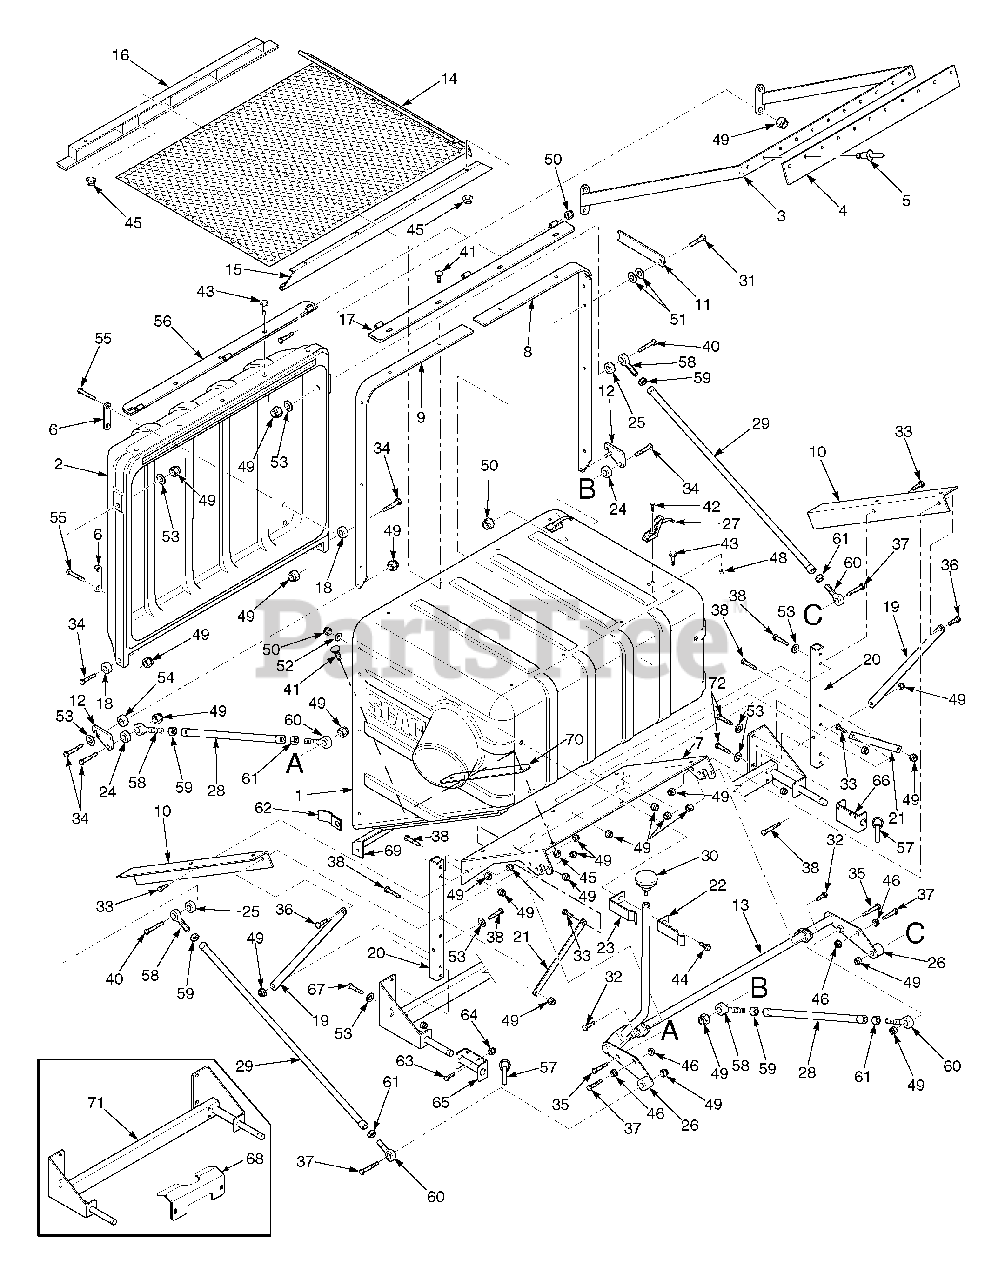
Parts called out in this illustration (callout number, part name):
1	Hopper, GC-STT-CS
2	Door, GC-CS
3	Sweeper Weldment, GC-CS
4	Pad, Rubber
5	Pop Rivet, 3/16 x .652
6	Plate, Stiffener
7	Support Frame, Hopper
8	Hinge Bracket, L.H.
9	Hinge Bracket, R.H.
10	Bracket, Hopper Support
11	Latch, Door Prop
12	Plate, Latch
13	Bellcrank Weldment, Upper
14	Debris Screen Weldment
15	Screen Support Weldment, Rear
16	Screen Support Weldment, Front
17	Hinge Weldment, Hopper
18	Spacer
19	Brace Stiffener, Short
20	Tube, Upright
21	Brace, Engine Mount
22	Latch, Dump Rod Inner
23	Latch, Dump Rod Outer
24	Spacer
25	Spacer
26	Spacer
27	Latch, Hood
28	Linkage Assembly, Lower
29	Linkage Assembly, Upper
31	Bolt, Hex Head 5/16-18 x 1-1/4
32	Bolt, Hex Head 3/8-16 x 3/4"
33	Bolt, Hex Head 3/8-16 x 1"
34	Bolt, Hex Head 3/8-16 x 1-1/2"
35	Bolt, Hex Head 3/8-16 x 1-3/4"
36	Bolt, Hex Head 3/8-16 x 1-1/4"
37	Bolt, Hex Head 3/8-16 x 2"
38	Bolt, Hex Head 3/8-16 x 2-1/4"
39	Bolt, Hex Head 5/16-18 x 3-1/2"
40	Bolt, Hex Head 3/8-16 x 3-1/2"
41	Bolt, Carriage 5/16-18 x 1"
42	Screw, #10-32 x 1/2"
43	Cap Screw, 5/16-18 x 3/4" Serr. Flan.
44	Cap Screw, 5/16-18 x 1" Serr. Flan.
45	Nut, 5/16-18 Serrated Flange
46	Nut, 3/8-16 Serrated Flange
47	Nut, 3/8-16 UNC Jam
48	Nut, #10-32 Elastic Stop
49	Nut, 3/8-16 Elastic Stop
50	Nut, 5/16-18 Elastic Stop
51	Washer, Special Wave
52	Washer, 5/16-.375 x .875 x .083 Flat
53	Washer, 3/8-.931 x .938 x .105 Flat
54	Bushing, Hopper Latch GC-CS
55	Bolt, Hex Head 3/8-16 x 3"
56	Hinge Weldment, Door
58	Rod End Male, 3/8-24 L.H. Thread
59	Nut, 3/8-24 UNF L.H. Thread
60	Rod End Male, 3/8-24 R.H. Thread
61	Nut, 3/8-24 UNF R.H. Thread
62	Alignment Bracket, GC-CS
63	Bolt, Hex Head 3/8-16 x 1"
64	Nut, 3/8-16 Elastic Stop
65	Hitch Bracket Weldment
66	Hitch Bracket Weldment, Floating
67	Bolt, Hex Head 3/8-16 x 3-3/4"
68	Support Bracket, Catcher
69	Bracket, Lower Stiffener
70	Retainer Strip, Hopper
71	Frame Weldment
